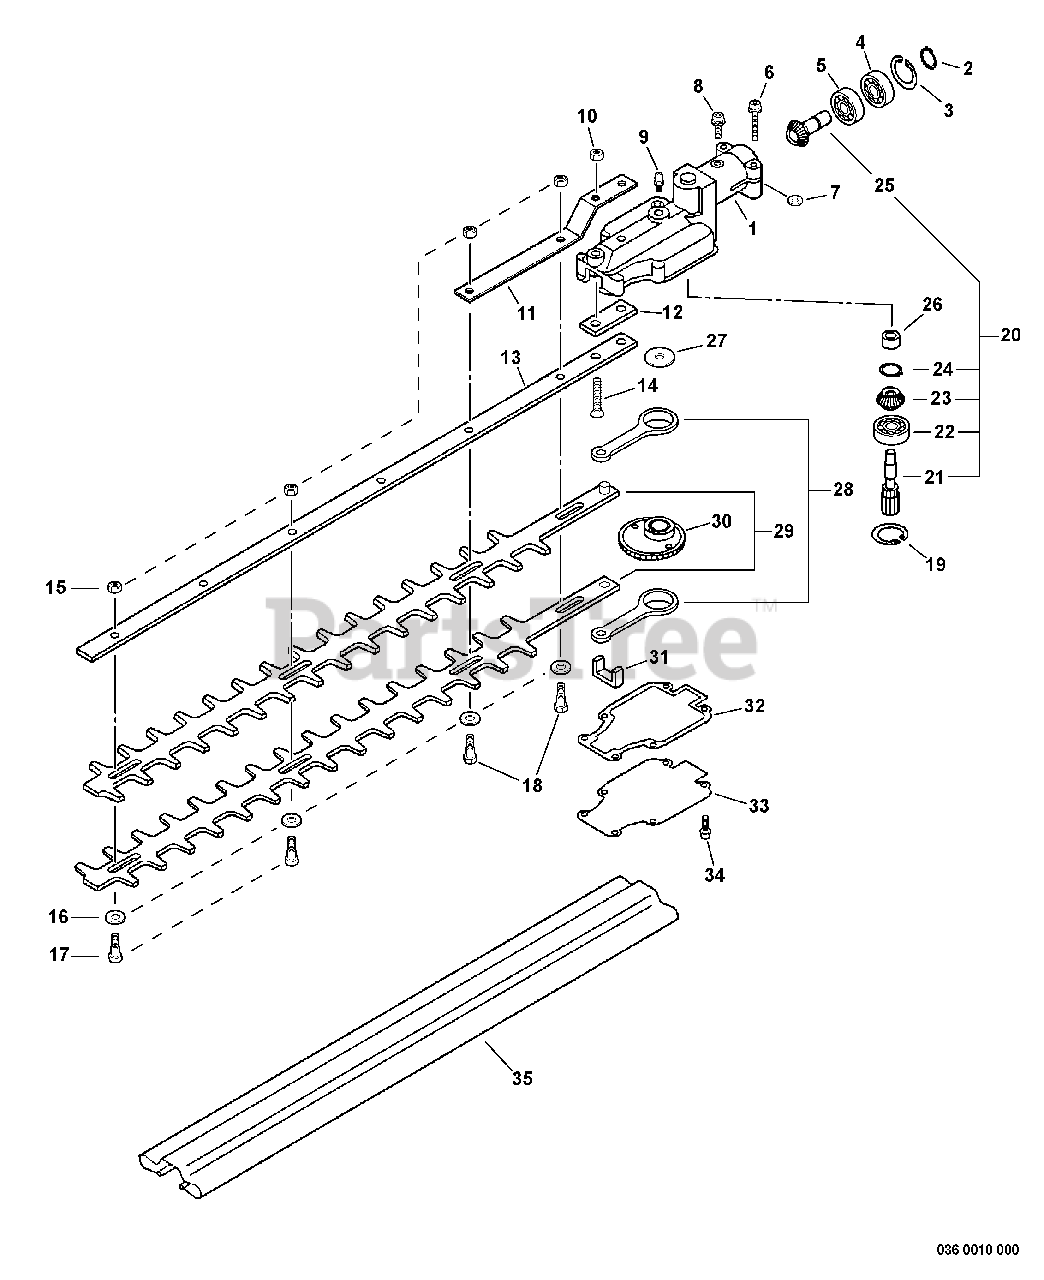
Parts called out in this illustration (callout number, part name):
1	CASE, GEAR
2	RING, SNAP Ø12
3	RING, RETAINING Ø24
4	BEARING, BALL 6901Z
5	BEARING, BALL 6901
6	BOLT 5×28
8	BOLT 5×12
9	FITTING, GREASE
10	NUT, HEX M6
11	BRACKET, BLADE
12	PLATE, EYE
13	SUPPORT, BLADE
14	SCREW 6×35
16	WASHER 6.5×15.5×0.6
18	BOLT 6×20
19	RING, RETAINING Ø24
20	GEAR KIT, SPUR
21	GEAR, PINION
22	BEARING, BALL 6901
23	GEAR, BEVEL
24	RING, RETAINING
25	GEAR, BEVEL
26	BEARING, NEEDLE
28	CONROD
29	CUTTER, 20"
32	GASKET, GEAR CASE
33	LID, GEAR CASE
34	BOLT 4×12
35	COVER, BLADE
